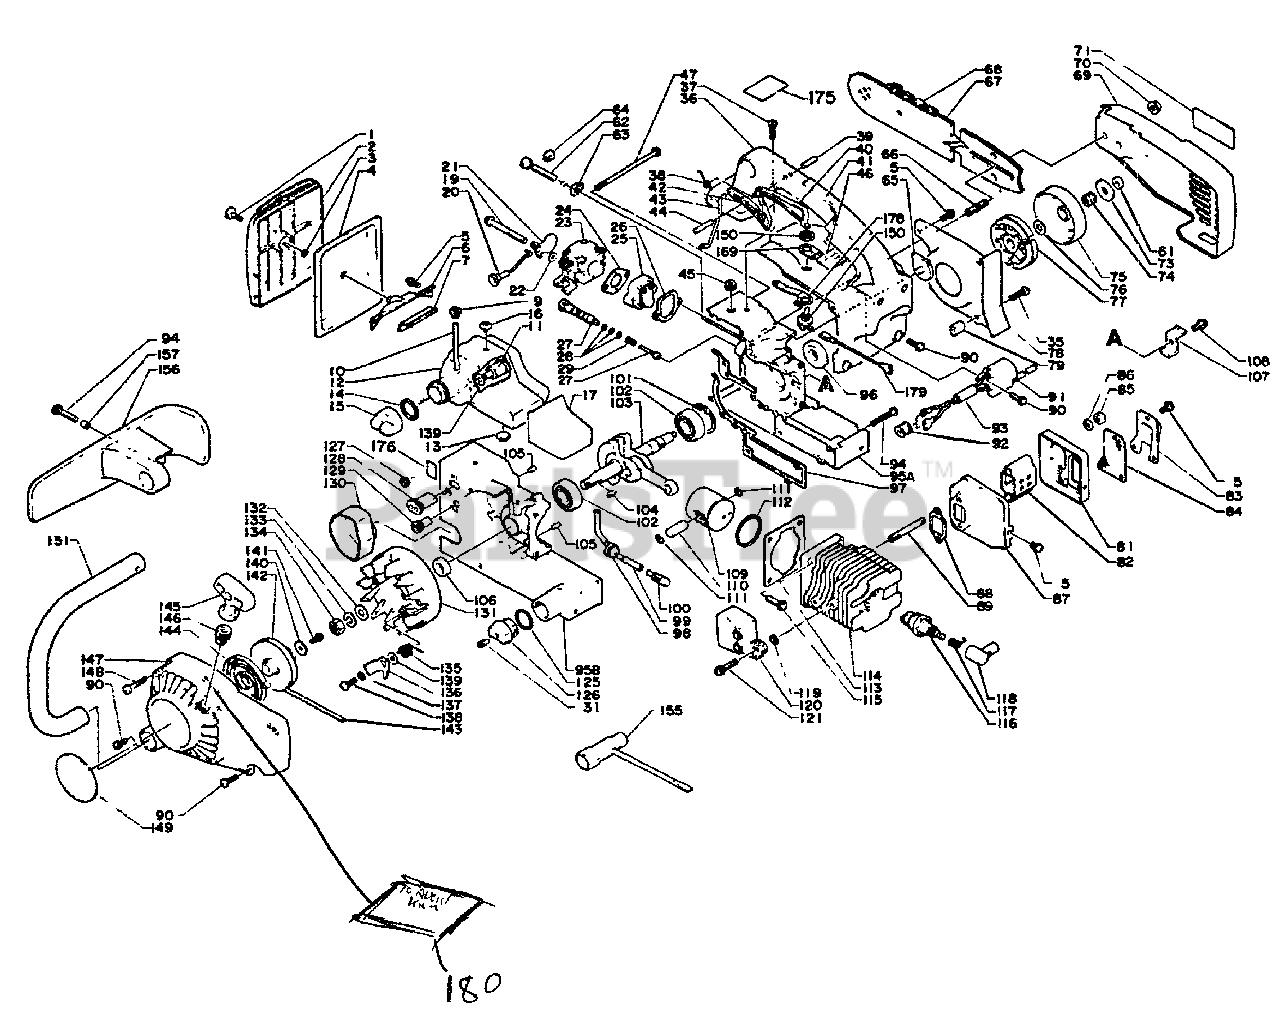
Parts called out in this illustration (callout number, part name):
1	THUMBSCREW
2	COVER, AIR FILTER
3	RING, RETAINING - 4
4	FILTER, AIR
5	SCREW - 4X10
6	BRACKET, AIR CLEANER
7	CUSHION
9	GROMMET
10	PIPE - FUEL
11	FILTER, FUEL
12	TANK, FUEL
13	CAP ASSY
14	GASKET, CAP
15	CAP
17	CUSHION
19	SCREW - 5X55
20	ROD, CHOKE
21	SHUTTER, CHOKE
22	WASHER
23	CARBURETOR C1S-K1D
24	GASKET, INTAKE
25	INSULATOR
26	GASKET, INTAKE
27	AUTO-OILER ASSY
28	O-RING - 5
31	VENT, TANK
35	SCREW - 4X20
36	HANDLE - TOP
37	SCREW - 4X18
38	SPRING
39	PIN - SPRING -- 5X18
40	LOCKOUT, THROTTLE
41	GRIP, HANDLE
42	TRIGGER, THROTTLE
43	ROD, THROTTLE
44	PIN - SPRING -- 5X25
46	LABEL
61	LOCKNUT - 6
62	SCREW, TENSIONER
63	TENSIONER, CHAIN
65	PLUG
66	STUD, GUIDE BAR
67	GUIDE BAR
68	SAW CHAIN
69	GUARD, SPROCKET
70	NUT - 6 -- FLANGE
71	LABEL - ECHO
74	BEARING, NEEDLE
75	DRUM, CLUTCH
77	CLUTCH ASSY
78	PLATE, SEAL
79	SPACER
81	LID, MUFFLER
82	BAFFLE, MUFFLER
83	GUIDE, EXHAUST
84	SCREEN, SPARK ARRESTOR
85	SCREW - 4X8
87	GUIDE, EXHAUST
88	GASKET, EXHAUST
90	SCREW - 4X16
91	COIL, IGNITION
94	SCREW - 4X30
95	CRANKCASE KIT
96	SEAL, OIL
97	GASKET, CRANKCASE
98	GROMMET
99	PIPE - OIL
100	FILTER, OIL
101	RING, RETAINING - 32
102	BEARING, BALL - 6201
103	CRANKSHAFT ASSY
105	PIN - LOCATING
106	SEAL, OIL
107	CATCHER, CHAIN
108	SCREW - 5X10
109	PISTON
110	PIN, PISTON
111	RING, RETAINING
112	RING, PISTON
113	GASKET, CYLINDER
114	CYLINDER
115	SCREW - 5X20
116	SPARK PLUG -- CJ-8Y
117	TERMINAL, SPARK PLUG CAP
118	CAP, SPARK PLUG
119	SPACER
120	COIL, IGNITION
121	SCREW - 5X22
125	O-RING - 16
126	CAP ASSY
128	GROMMET
129	GROMMET
130	SEAL
131	FLYWHEEL
132	WASHER - 8
133	LOCKWASHER - 8
135	SPRING, RETURN
136	PAWL, STARTER
138	SCREW
139	WASHER - 5
139	STARTER ASSY
140	WASHER - 4
141	SCREW - 4X10
142	REEL, ROPE
143	ROPE, STARTER - 3.5X850
144	SPRING, REWIND
145	GRIP, STARTER
146	GUIDE, ROPE
147	CASE, STARTER
148	SCREW - 4X25
149	LABEL - ECHO
150	IGNITION SWITCH KIT
151	HANDLE - FRONT
155	T-WRENCH - 10X19mm
156	GUARD
169	LABEL - SWITCH
175	LABEL - NOISE
176	LABEL - CHOKE
178	PLATE - GROUND
179	LEAD - GROUND
180	SCREW - 4X16
181	SCREW - 4X22
183	PLATE, PREVENT
192	PLATE, STARTER
